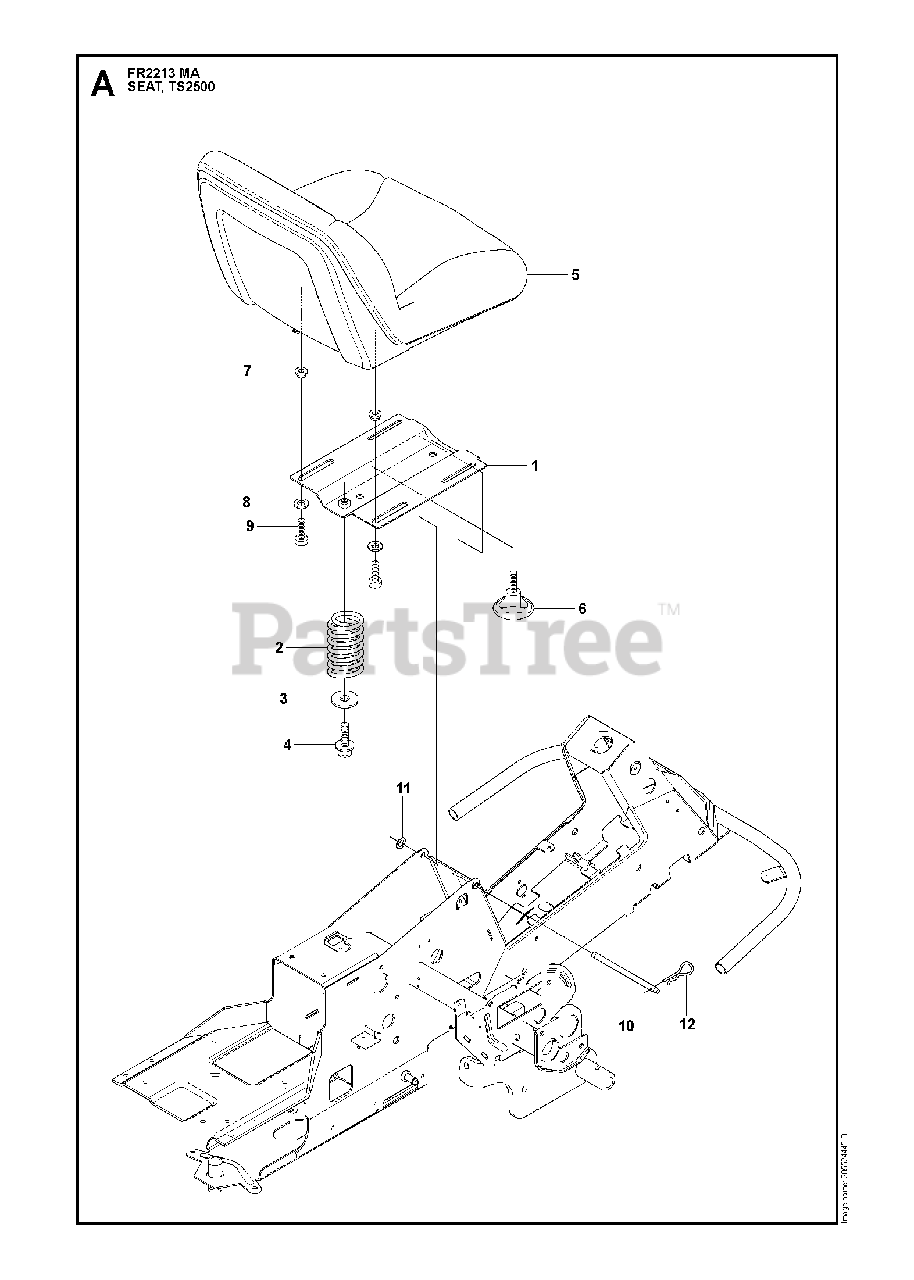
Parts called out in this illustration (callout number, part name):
2	SEAT SPRING
4	SCREW M10X25
6	ADJUSTING KNOB
11	RETAINING RING SGA 10
